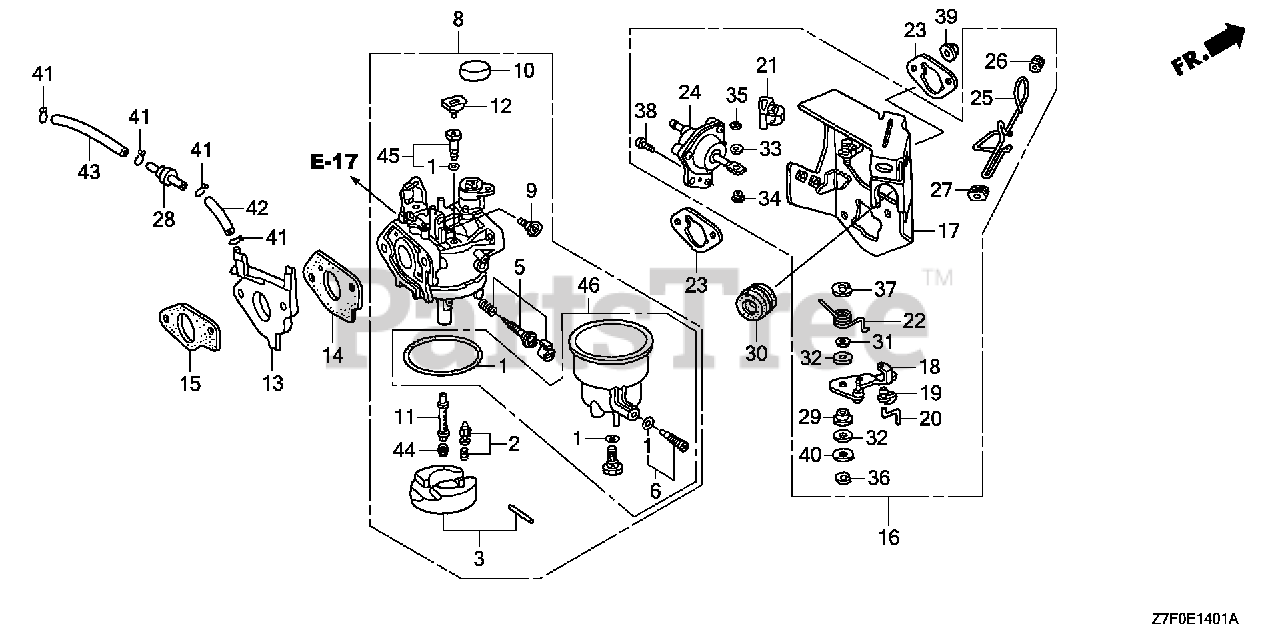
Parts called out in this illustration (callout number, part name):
1	GASKET SET
2	VALVE SET, FLOAT
4	CHAMBER SET, FLOAT
6	SCREW SET, DRAIN
7	SCREW SET
8	CARBURETOR ASSY. (BE89L A)
9	SCREW, THROTTLE STOP
10	CAP, CHOKE DUST
11	NOZZLE, MAIN
12	COLLAR, SETTING
13	INSULATOR, CARBURETOR
14	GASKET, CARBURETOR
15	GASKET, INSULATOR
16	STAY ASSY., MANUAL CHOKE (NOT AVAILABLE)
17	STAY, SOLENOID
18	LEVER, CHOKE
19	JOINT, ROD
20	ROD, CHOKE
21	STOPPER, CHOKE ROD
22	SPRING, MANUAL CHOKE
23	GASKET, AIR CLEANER
24	DIAPHRAGM ASSY.
25	ROD, CHOKE CONTROL
26	GROMMET, CHOKE ROD
27	GUIDE, CHOKE ROD
28	VALVE, DASHPOT CHECK
29	BUSH, ARM PIVOT
30	GROMMET, FENDER
31	WASHER, CHOKE LEVER
32	SEAL, CHOKE LEVER
33	WASHER, THRUST (2.7X8)
34	COLLAR, LEVER
35	E-RING (2MM)
36	E-RING (4MM)
37	E-RING (7MM)
38	SCREW, PAN (5X12)
39	NUT, FLANGE (6MM)
40	WASHER, PLAIN (5MM)
41	CLIP, TUBE (B7)
42	BULK HOSE, VACUUM (3.5X8000) (3.5X75)
43	BULK HOSE, VACUUM (3.5X8000) (3.5X130)
44	JET, MAIN (#102)
44	JET, MAIN (#105)
44	JET, MAIN (#108)
45	JET SET, PILOT (#45)
46	BOLT KIT, FUEL CHAMBER
